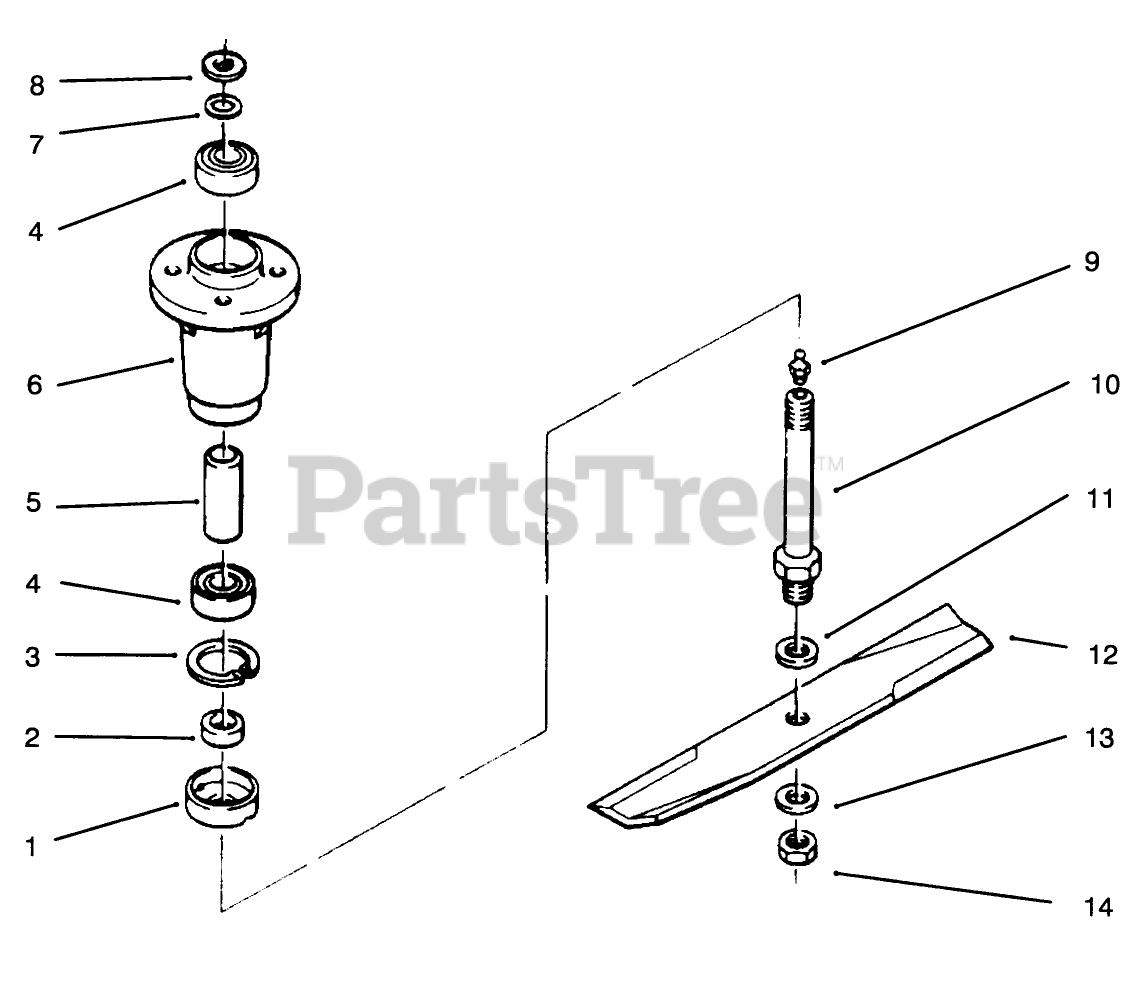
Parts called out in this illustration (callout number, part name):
1	CUP-SPINDLE
2	SPACER-BLADE
3	RING-RETAINING
4	BEARING-BALL
6	HOUSING-SPINDLE
7	O RING
8	Washer
9	FITTING-GREASE
10	SHAFT-SPINDLE
11	Washer
12	S/A BLADE KIT
13	WASHER-FLAT
14	NUT-JAM
